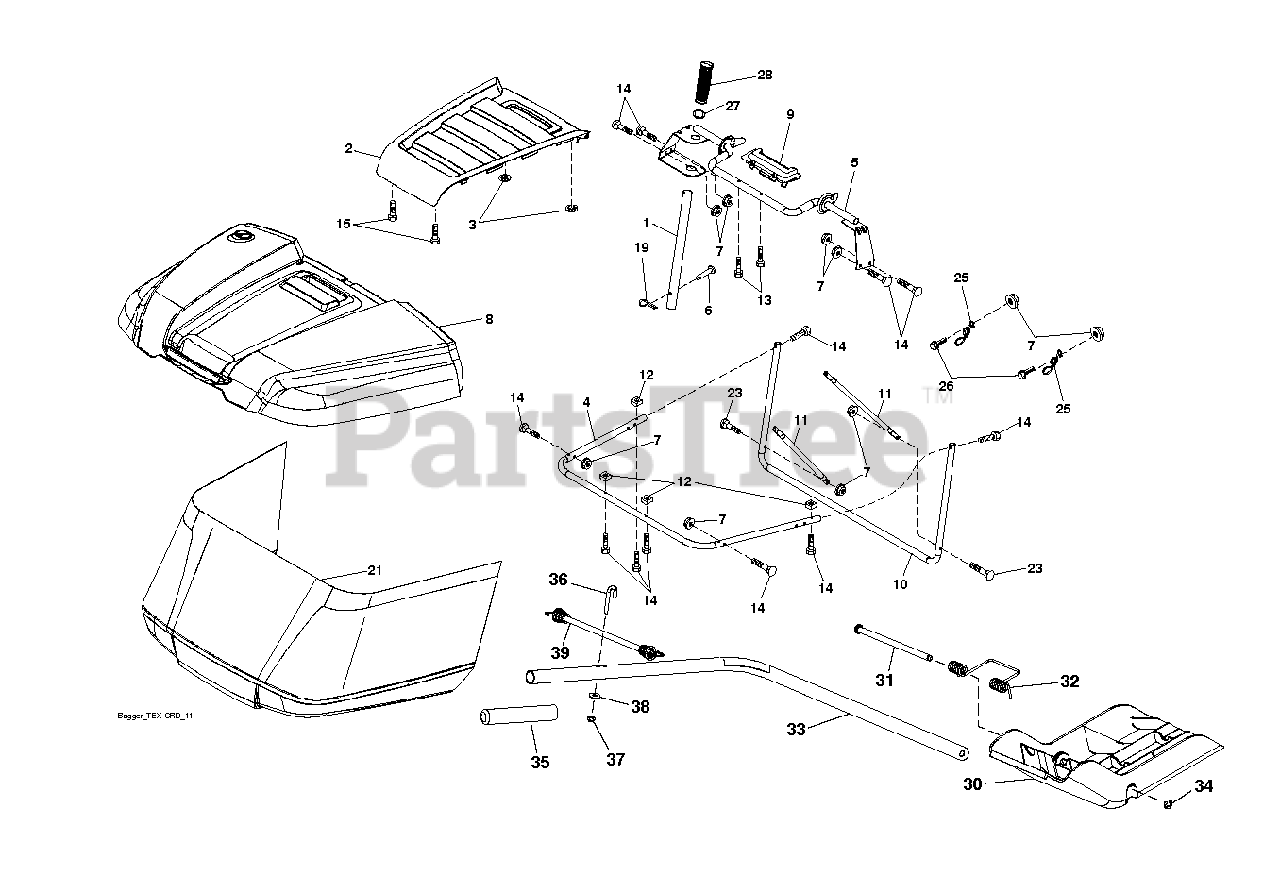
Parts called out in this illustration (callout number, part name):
1	TUBE.HANDLE.BAGGER.CRD/SRD.BLA
2	APPLIQUE.TOP.BAG.SRD.ORANGE
3	NUT.PUSH.156
4	SUBASM.TOP.TUBE.TEX.CRD
5	FRAME.ASM.TOP.BAGGER.SRD
6	RIVET,DRILLED
7	NUT T
8	BAGGER.TOP.SRD.APPLIQUE
9	INSERT.HANDLE.BAGGER.(2 2)
10	FRAME FRAME.FRONT.TEX.CRD
11	BRACE BRACE SIDE TUBE
12	NUT.SQUARE.1/4
13	SCREW.1/4X1.150.HXWSH
14	BOLT.SHOULDER.HX.WSH.1/4X1.150
15	SCREW,#8.FLAT.HEAD.DRILL.TIP
19	PIN.COTTER.5/16.BOW TI
21	BAG SUBASM. TEX CRD GEN 2 HUSQ
25	SPRING.LATCH.BAGGER.SRD
26	SCREW HEX CRT
27	RB GROMMET.RUBBER.SRD
28	GRIP.HANDLE.BLACK
30	PLUG PLUG
31	PIN PIN.HINGE
32	SPRING SPRING DOUBLE TORSION
33	SHAFT SHAFT TEX CRD MULCH PLU
34	E-RING.5/16"
35	GRIP GRIP MULCH PLUG HAND
36	BOLT BOLT J
39	BUBGEE BUBGEE TEX CRD
